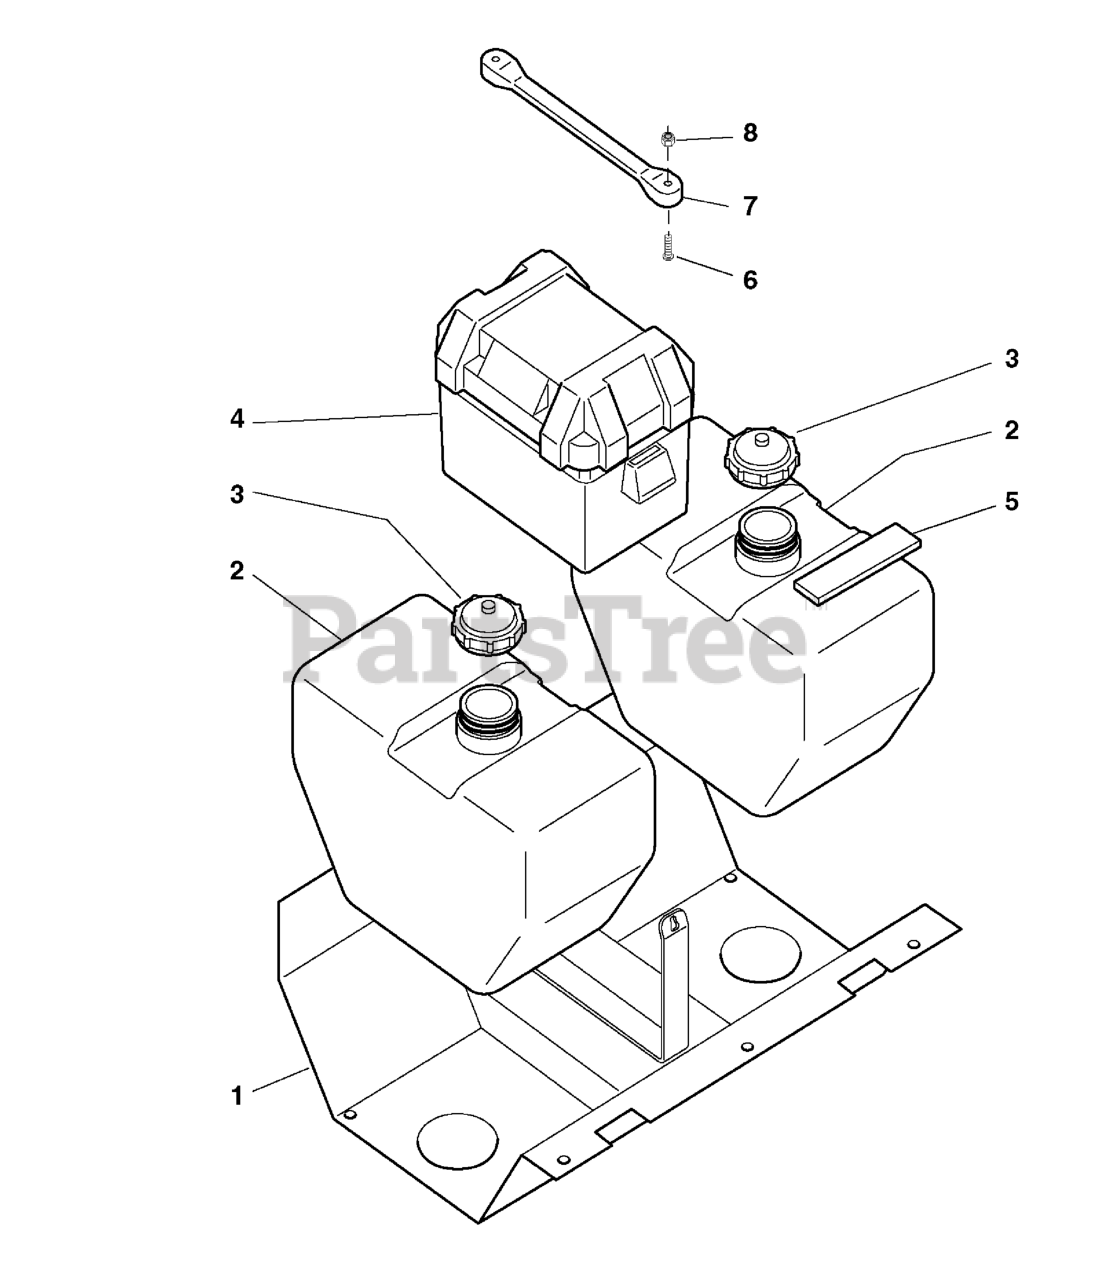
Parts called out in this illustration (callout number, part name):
1	FUEL TANK MOUNT PAN
2	FUEL TANK, 4 Gallon
3	CAP, Fuel Tank
4	BOX, Battery
5	RUBBER PAD
6	SCREW, #10-24 X 1 RS, CZ
7	RUBBER STRAP
8	NUT, #10-24 Hex Nylon Lock
